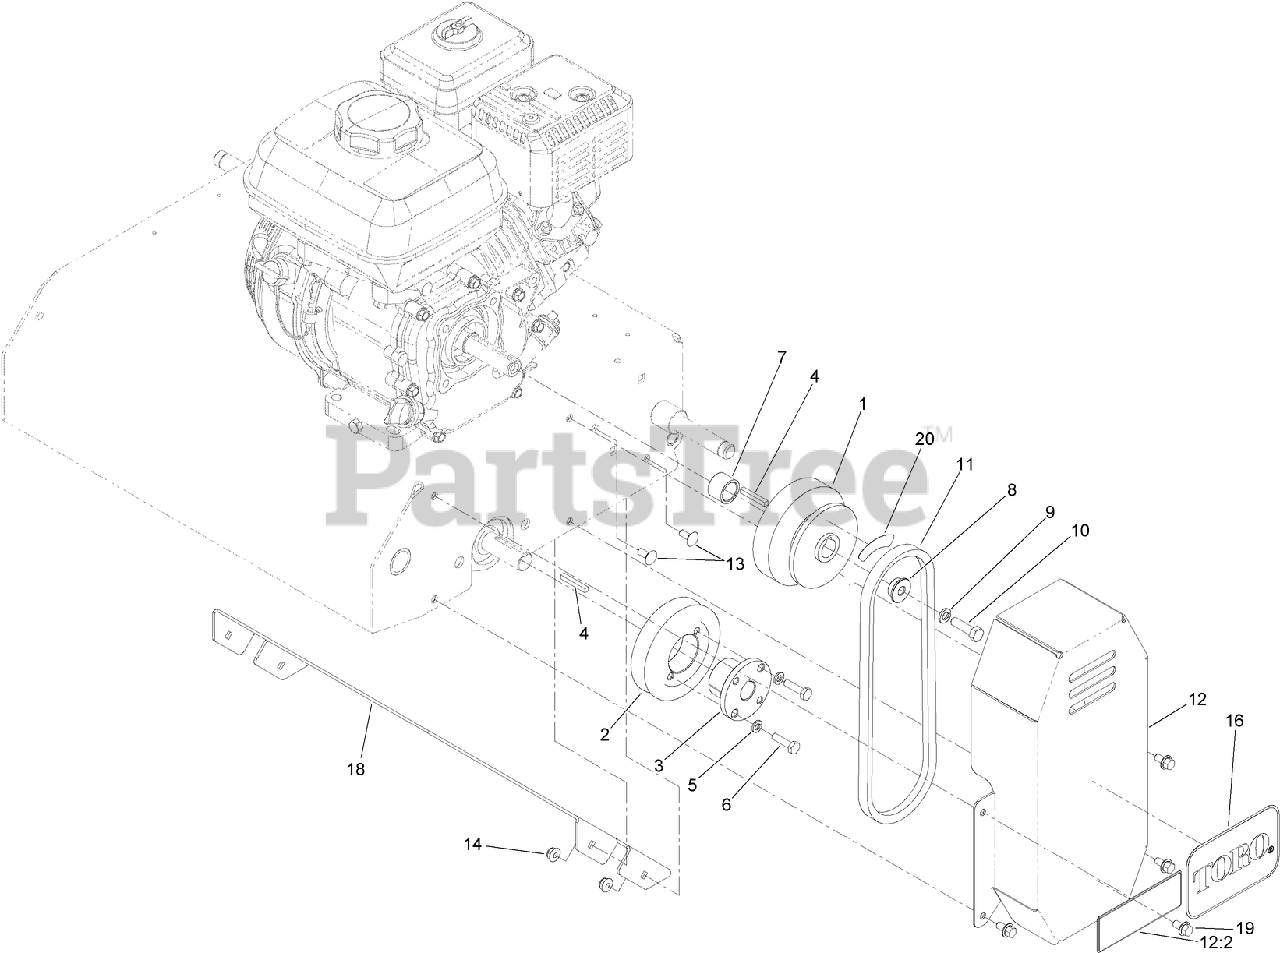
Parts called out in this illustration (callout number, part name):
1	CLUTCH-CENTRIFUGAL
2	SHEAVE-TAPER LOCK
3	BUSHING-TAPER LOCK
4	KEY-SQUARE
5	WASHER-LOCK
6	SCREW-HH
7	SPACER
8	BUSHING
9	WASHER-LOCK
10	SCREW-HH
11	V-BELT
12	BELT GUARD ASM
12:2	DECAL-DANGER
13	SCREW-CARR
14	NUT-HF
16	DECAL
18	BAFFLE-DEFLECTOR
19	SCREW-HHF
20	DECAL-WARNING
